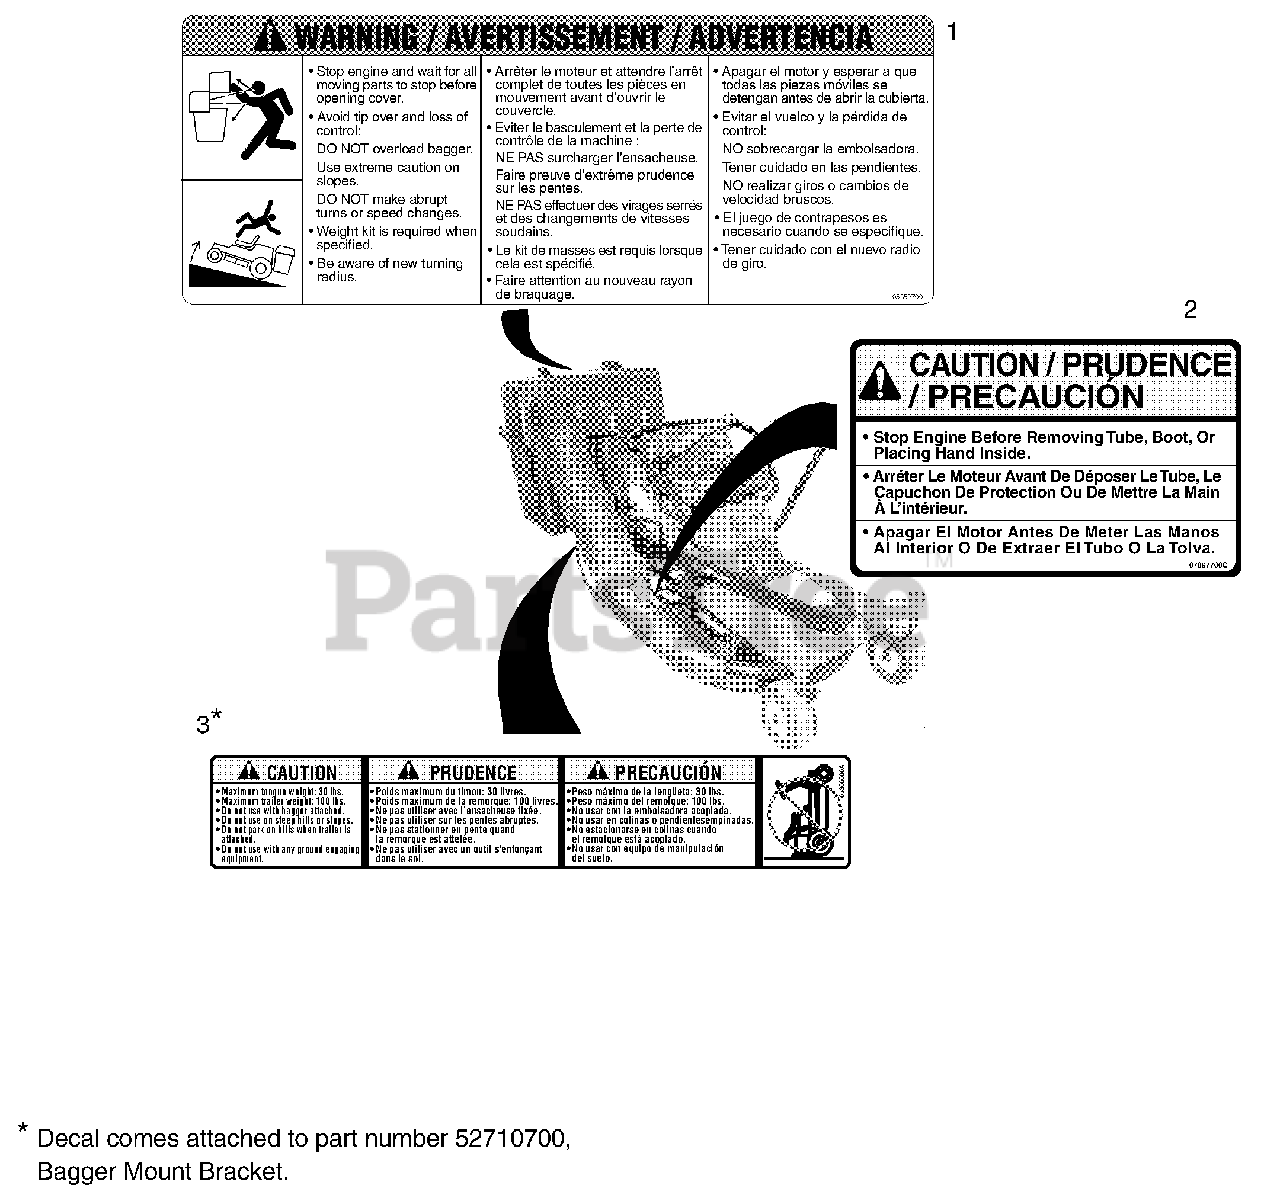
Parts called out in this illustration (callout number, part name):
1	DECAL, BAGGER COVER
2	DECAL-BOOT CAUTION
3	DECAL-HITCH 100#
